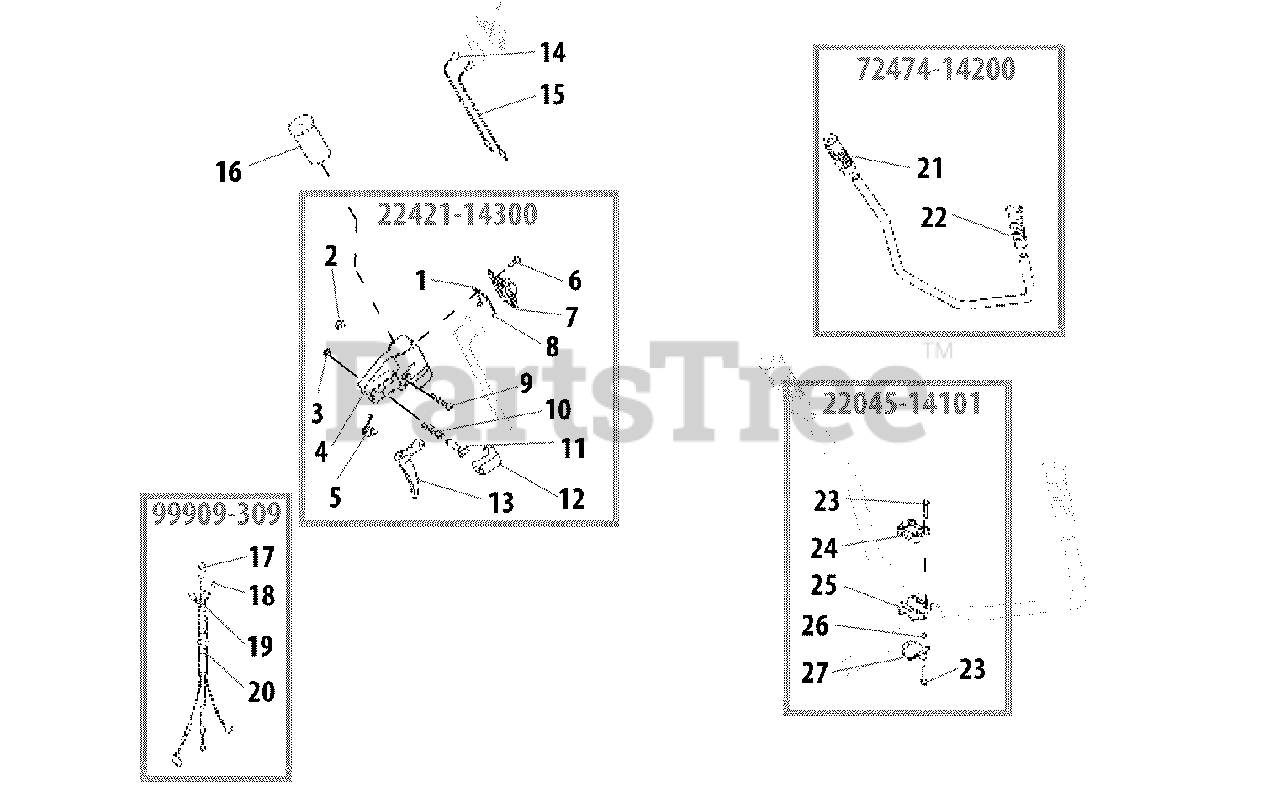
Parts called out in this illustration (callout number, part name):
1	PLATE, RIGHT GROUND
2	NUT, NYLON
3	RING, SNAP
4	BODY, THROTTLE
5	SPRING, RETURN
6	SCREW, TAPPING
7	SWITCH, ON-OFF
8	PLATE, LEFT GROUND
9	SCREW
10	SPRING
11	LOCKOUT, THROTTLE
12	BUTTON, THROTTLE LOCK
13	TRIGGER, THROTTLE
14	WIRE, RIGHT LEAD
15	WIRE, LEFT LEAD
17	CABLE, THROTTLE
18	WIRE
19	WIRE
20	PROTECTOR
21	GRIP, THROTTLE
22	GRIP
23	BOLT M5×25
24	BRACKET, UPPER
25	BRACKET, HANDLE
26	WASHER, FLAT 5.5×10×0.8
27	CLAMP, LOWER
A	THROTTLE CONTROL ASSY
A	CONTROL CABLE ASSY
A	HANDLE ASSY
A	HANDLE BRACKET KIT
